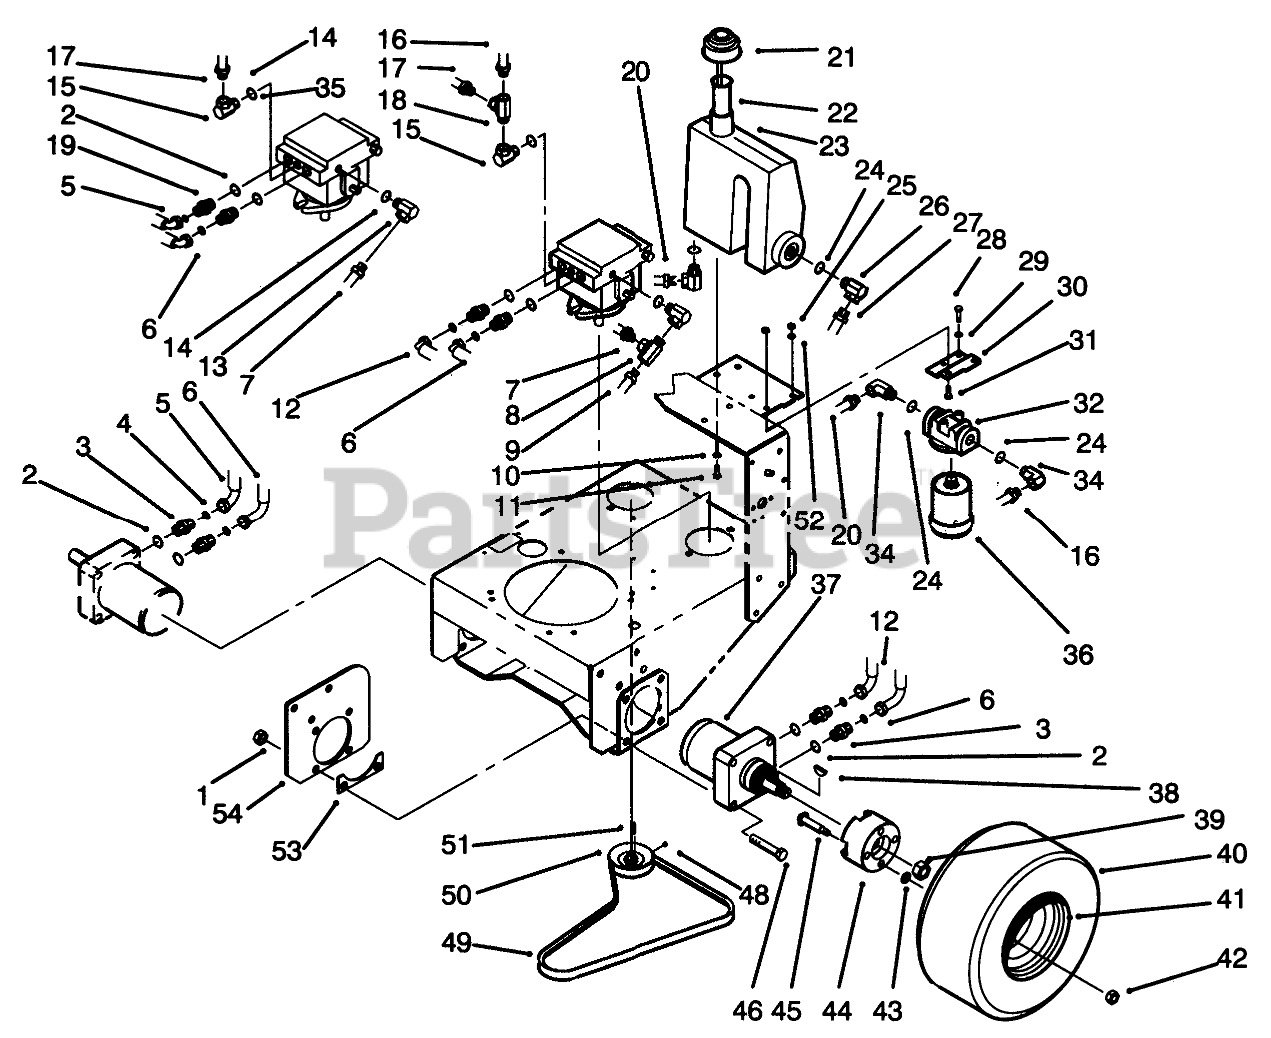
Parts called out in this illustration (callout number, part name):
1	NUT-LOCK, NI
2	O-RING
3	FITTING-STRAIGHT
4	O-RING
5	HYDRAULIC HOSE ASM
6	HYDRAULIC HOSE ASM
7	HYD HOSE ASM
8	FITTING-HYD, TEE
9	HYDRAULIC HOSE ASM
10	WASHER-LOCK
11	SCREW-HH
12	HYDRAULIC HOSE ASM
13	FITTING-HYD, 90 DEG
14	O-RING
15	SWIVEL-PIPE, FEMALE
16	HYDRAULIC HOSE ASM
17	HYD HOSE ASM
18	FITTING-HYD, TEE
19	FITTING-STRAIGHT
20	HYD HOSE ASM
21	OIL CAP ASM
22	SCREEN-FILLER
23	Reservoir-Oil
24	O-RING
25	NUT-LOCK, NI
26	FITTING-HYD, 90 DEG
27	HYDRAULIC HOSE ASM
28	SCREW-HH
29	WASHER-LOCK
30	FILTER MOUNTING BRKTR
31	SCREW-HH
32	FILTER HD ASM
34	FITTING-HYD, 90 DEG
35	O-RING
36	CARTRIDGE-FILTER, OIL
37	WHEEL MOTOR ASM
38	KEY-WOODRUFF
39	Nut (Incl. w/Motor)
41	WHEEL
42	NUT-LUG
43	PUSHNUT
44	HUB-WHEEL
45	SCREW-HH
46	SCREW-HH
48	SCREW-SET, HS
49	BELT-V
50	PUMP PULLEY
51	KEY-PUMP
52	WASHER-PLAIN
53	Spacer
54	Plate-Frame
